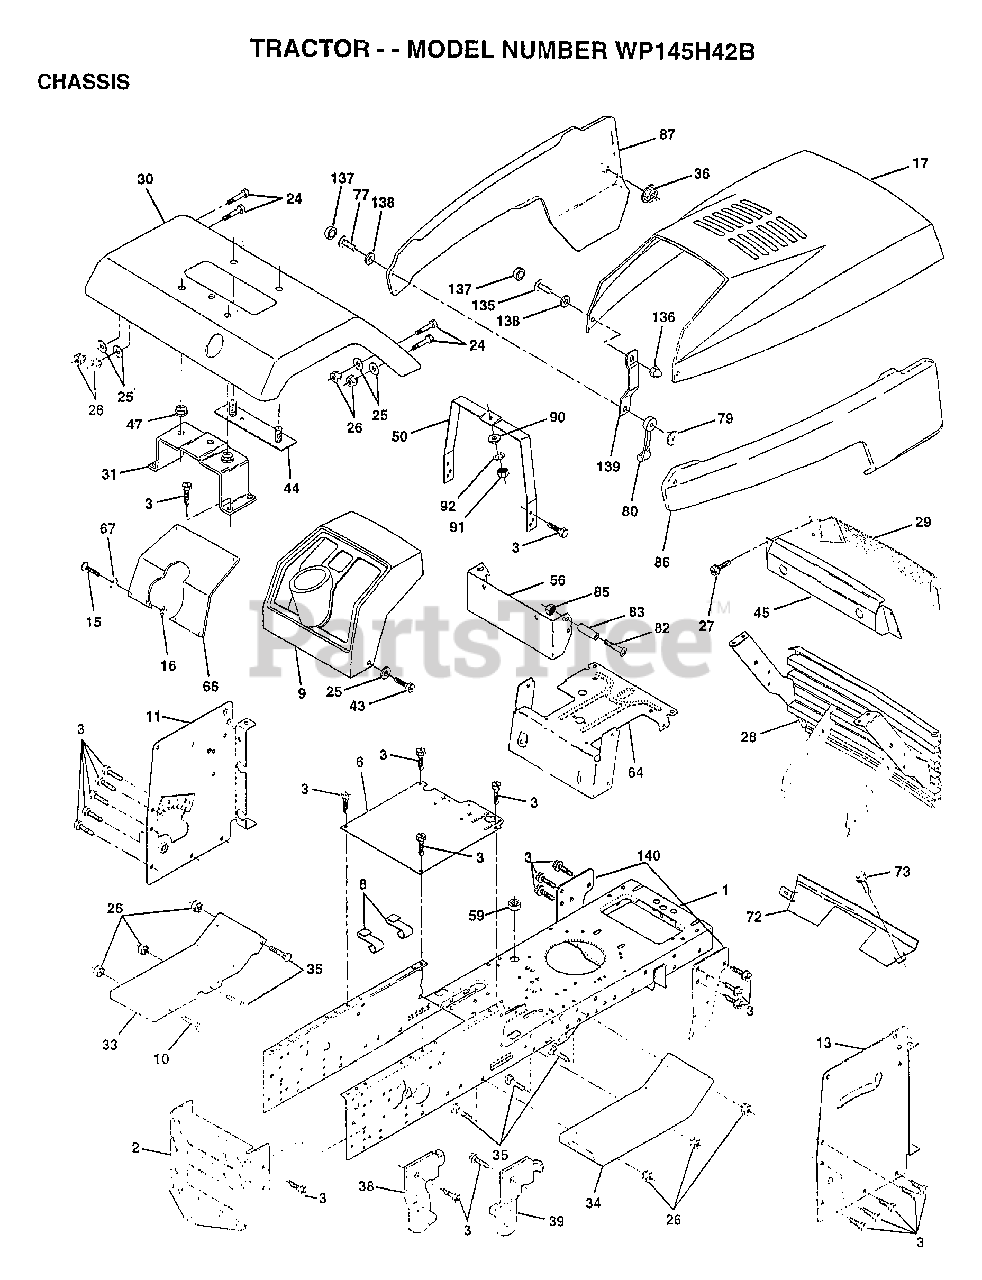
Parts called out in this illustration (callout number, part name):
1	CHASSIS ASM
3	SCREW
6	SADDLE
8	"CLIP,INSULATOR"
9	DASHBOARD BLACK
11	PANEL.DASH.LH.
13	PANEL.DASH.RH.
15	SCREW
24	BOLT
25	WASHER
26	NUT
28	GRILLE ASM PNT
29	PANEL.DASH.RH
30	FENDER.PNT.
31	BRKT.ASM.FENDER
33	FOOTREST.LH.LT/GT
34	FOOTREST.RH.LT/GT
35	BOLT
36	PAL NUT LT
38	BRACKET ASM LH
39	BRACKET ASM RH
43	SCREW GTV
44	STRAP ASM FENDER
45	BEZEL.ASM.
47	NUT-PUSH YT
50	DASH.SUPT.YP/HUSQ
56	EXT DASH LTYT
64	DASH.LOWER.LT
66	"PLATE-DASH,SLSCR"
67	WASHER
72	STRAP.GRILLE.PNT.
73	SCREW CRT
77	SCREW
79	WELDNUT
80	HOOD LATCH T
82	SCREW
83	SPACER LT
87	"PANEL SIDE,LH"
90	WASHER PM
92	LOCKWASHER
135	SCREW.10-24X3/8.
136	ACORN NUT RB
137	SNAP CAP LT
138	WASHER LT
139	BKT.SPT.HOOD/PANL
140	BRKT SUSPENSION
